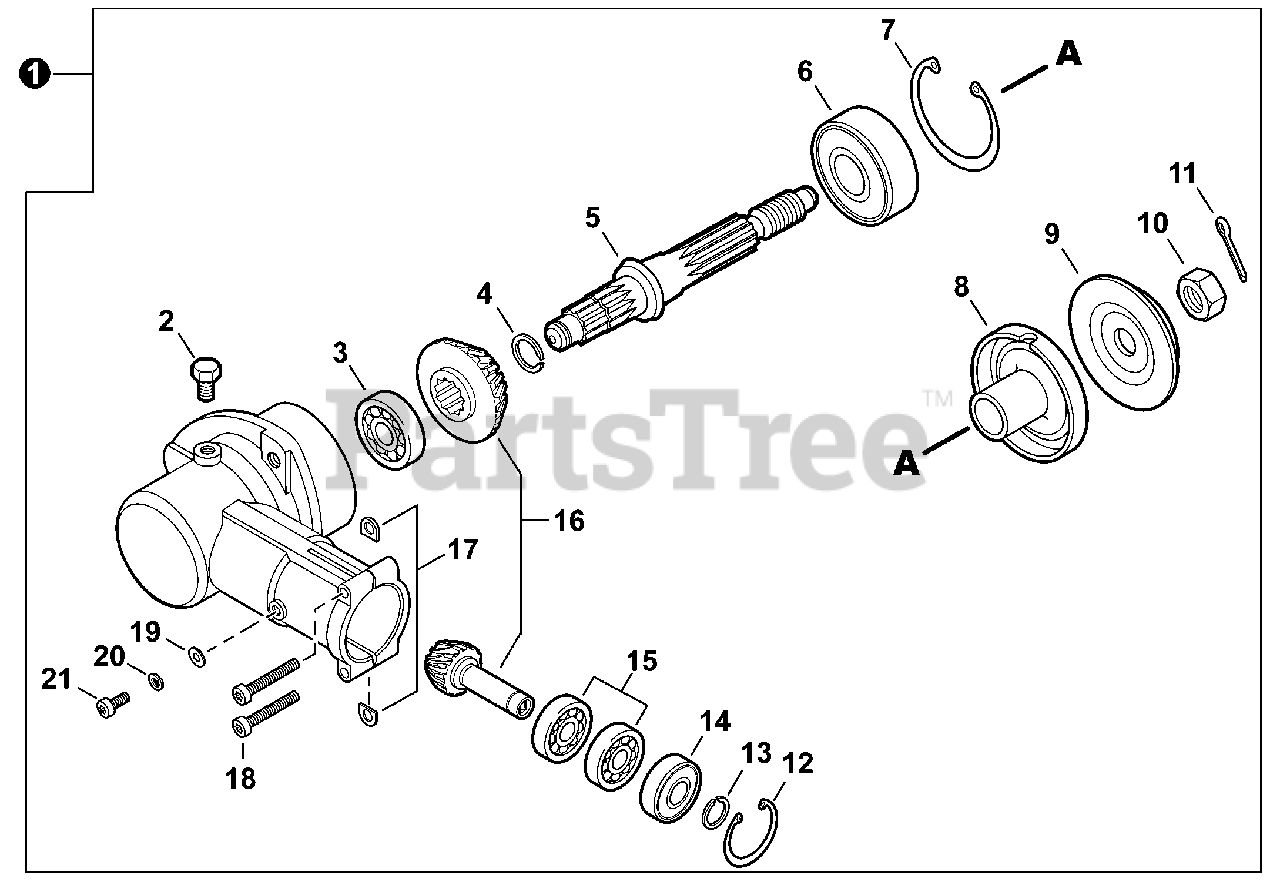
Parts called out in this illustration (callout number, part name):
1	GEAR CASE ASSY
2	BOLT M8×8
3	BEARING, BALL 629
4	RING, SNAP Ø12
5	SHAFT, GEAR
6	BEARING, BALL 6302
7	RING, SNAP Ø42
8	PLATE, ADAPTOR - UPPER
9	PLATE, ADAPTOR - LOWER
10	NUT 10×1.25 LH
11	PIN, COTTER 2×22
12	RING, SNAP Ø22
13	RING, SNAP Ø10
14	BEARING, BALL 6900Z
15	BEARING, BALL 6900
16	GEAR SET
17	D-WASHER
18	BOLT, TORX 5×25
19	WASHER, FLAT 5.5×10×0.8
20	WASHER, SPRING 5
21	BOLT, TORX 5×12
